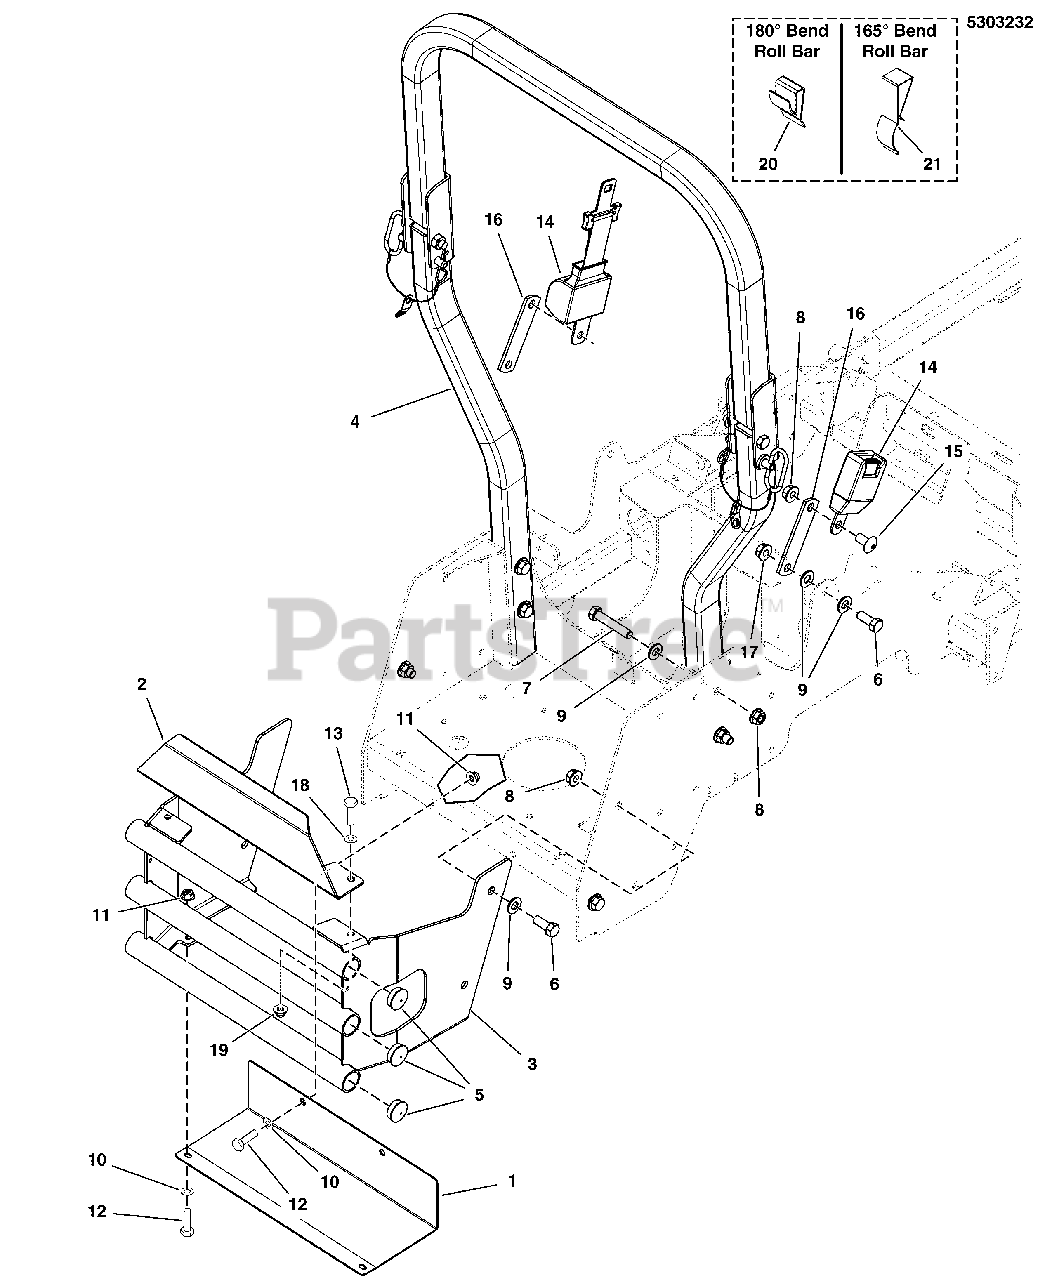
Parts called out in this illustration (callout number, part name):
1	PLATE, HEAT SHIELD, IS700 - BLK
2	PLATE, CARB PROTECTOR - ORG
3	WELD, BUMPER - IS700 - ORG
4	ROPS (Call 1-800-933-6175 x708 if replacing a ROPS)
5	PLUG, PANEL, 1.25 - BLACK
6	BOLT, 1/2-13 X 1-1/4 GD5 YZ
7	BOLT, 1/2-13 X 2-3/4 GD5 YZ
8	NUT, 1/2-13 HEX NYLOCK FLANGE
9	WASHER, 1/2 SAE
10	WASHER, 5/16 SAE
11	NUT, 5/16-18 HEX NYLOCK FLANGE
12	BOLT, 5/16-18 X 3/4 GD5
13	BOLT, 3/8-16 X 1 GD5 YZ
14	SEAT BELT, RETRACTING - ASSM
15	SCREW, 1/2-13 X 1.00, SHCS
16	PLATE, SEAT BELT ANCHOR - BLK
17	NUT, 1/2-13 HEX NYLON LOCK
18	WASHER, 3/8 SAE
19	NUT, 3/8-16 HEX NYLOCK FLANGE
20	ANTI-RATTLE SPRING, FEMCO #230328972 (SV)
21	ANTI-RATTLE SPRING, ROPS, 165 DEGREE (SV)
